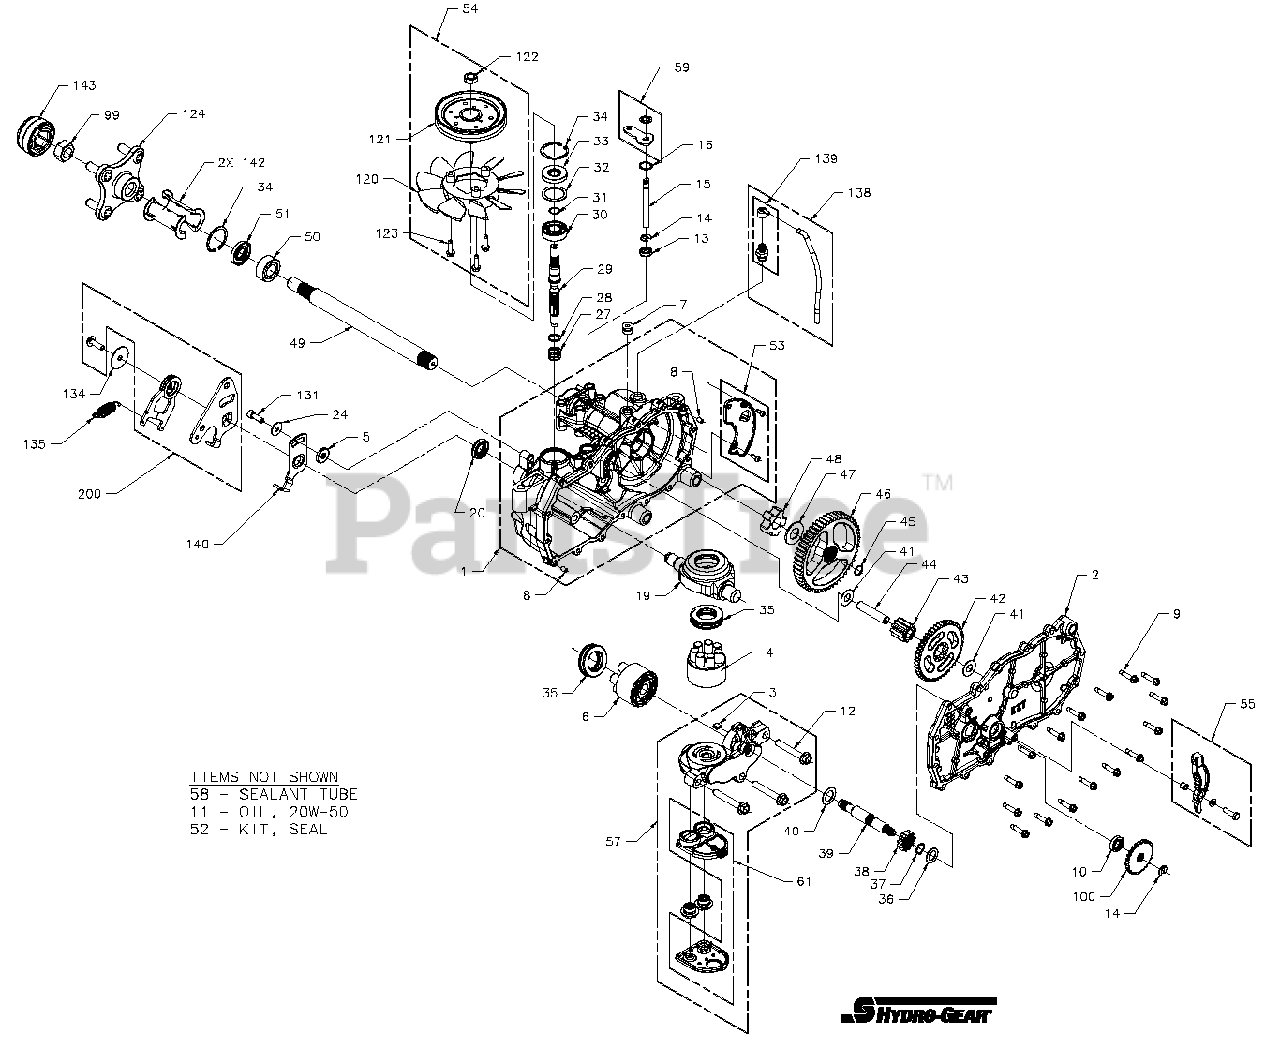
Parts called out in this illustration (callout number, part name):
4	ASSEMBLY, PUMP BLOCK (7P-10CC)
6	ASSEMBLY MOTOR BLOCK (5P-10CC)
10	KIT, BRAKE SEAL
13	SEAL, LIP .375 X .75 X .25
14	RING, RETAINING .375 EXT
19	SWASHPLATE, TRUNNION, MACHINED
20	SEAL, LIP 18 X 32 X 7
28	WASHER .591 X .787 X .040
29	SHAFT, INPUT
30	BEARING, BALL 17MM ID X 40MM OD X 12MM
33	SEAL, LIP 17 X 40 X 7
34	RING, RETAINING
35	BEARING, THRUST 30 X 52 X 13
45	RING, SPIRAL RETAINING
50	BUSHING, AXLE
51	SEAL, LIP .75 X 1.5
52	KIT SEAL
55	KIT BRAKE ARM
58	SEALANT TUBE 10.3 oz
99	NUT, HEX 3/4-16
100	DISC, COG BRAKE
121	PULLEY 4/5 X 1.625
124	KIT, HUB 1/2-20
134	WASHER 1/5 X .34 X .062
135	SPRING, EXTENSION
